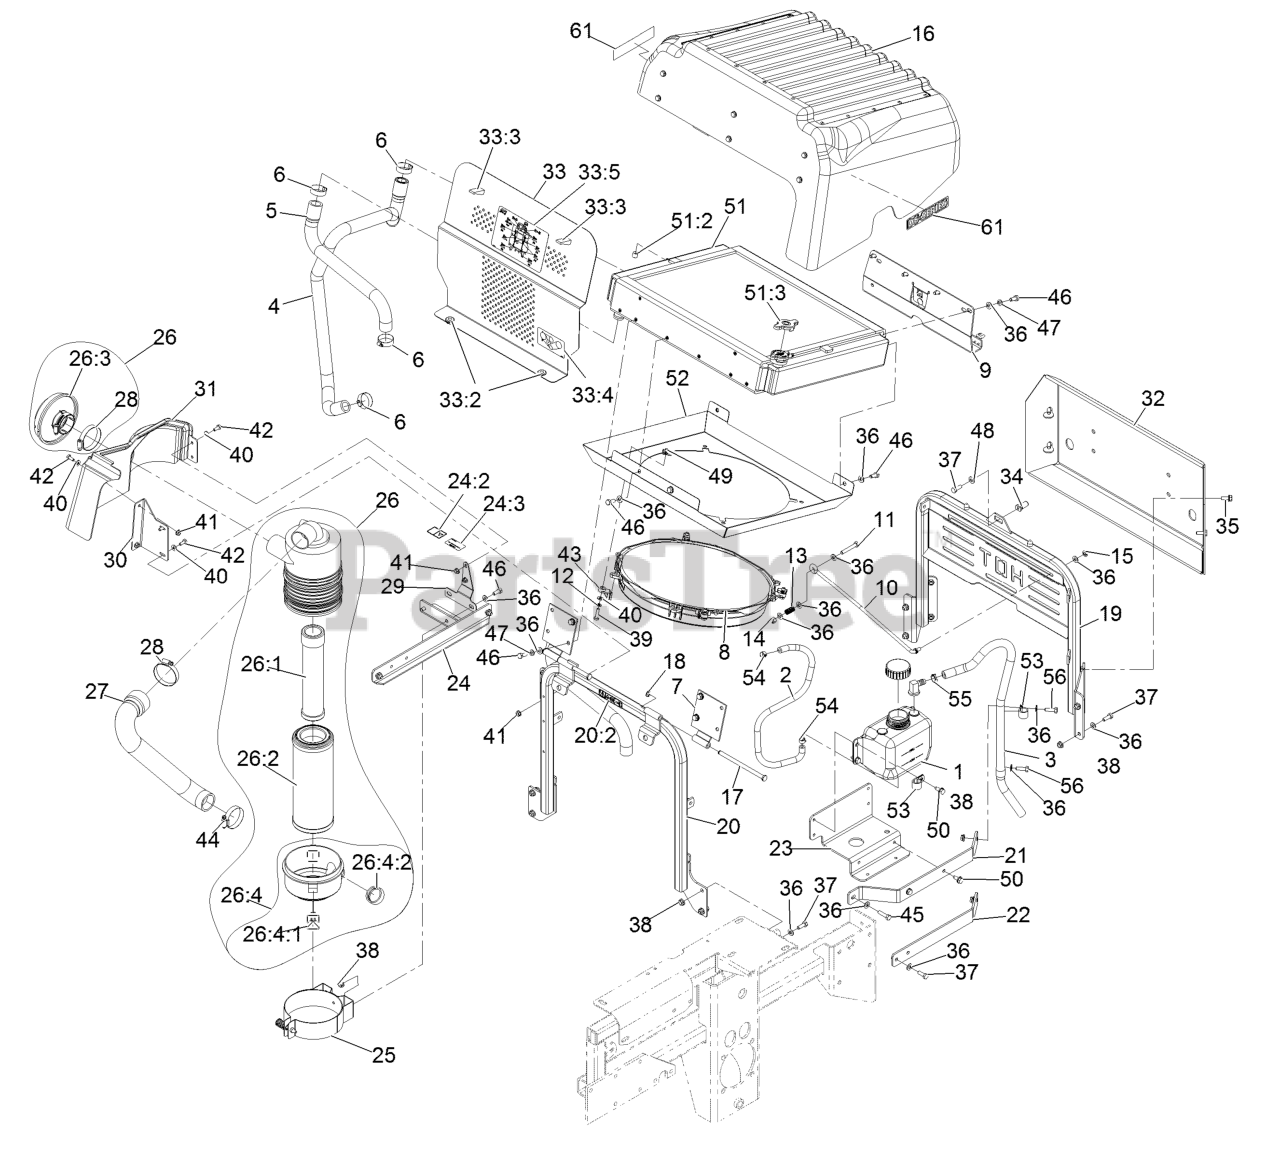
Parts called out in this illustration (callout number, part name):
1	TANK, OVERFLOW W/CAP
2	HOSE, .313 I.D.X 25.0 REI
3	HOSE, .500 I.D. X 30" EPD
4	HOSE,RADIATOR LOWER D902
5	HOSE,RADIATOR UPPER D902(
6	CLAMP-HOSE
7	WLD,HINGE PLATE
8	FAN- ELECTRIC
9	ASM-LATCH PLATE
10	ROD,PROP
11	SCREW-HH
12	SCREW-HH
13	SPRING,LOCK PIN
14	NUT-LOCK, NI
16	HOOD ASM, D902
19	WLD,REAR GUARD
20	ASM, RAD. MOUNT W/ DECALS
20:2	DECAL-DANGER
22	RIB, BOTTOM
23	BRACKET, BOTTLE-HYDRO TAN
24	Wld, Air Cleaner Mount
24	ASM,AIR CLNR BRKT W/DECAL
24:2	DECAL-WARNING
24:3	DECAL-CAUTION
25	BRACKET-FILTER, AIR
26	FILTER-AIR
26:1	FILTER-AIR, SAFETY
26:2	FILTER-AIR
26:3	HOOD-CLEANER, 2" AIR INTA
26:4	COVER-FILTER, AIR
26:4:1	CLIP-CLEANER, AIR
26:4:2	EJECTOR, NELSON AIR CLEAN
27	HOSE,AIR INTAKE D902(8015
28	CLAMP-HOSE
29	BRACKET,REAR COVER
30	BRACKET,FRONT COVER
31	PANEL, SIDE
32	WLD,REAR BUMPER
33	ASM,PANEL W/ DECALS LXS L
33:2	GROMMET
33:3	LATCH-SWELL
33:4	DECAL-BELT PUMP ROUTING
33:5	Decal-Service Aid
34	PIN,LATCH
35	SCREW-HHF
36	WASHER-PLAIN
37	SCREW-HH
39	SCREW-HH
40	WASHER-FLAT
42	SCREW-HH
43	MOUNT,FAN
44	CLAMP-HOSE
45	SCREW-HH
46	SCREW-HH
47	WASHER-LOCK
48	WASHER-SPRING
49	Nut-Retainer-Panel 1/4-20
50	Screw-HWH 5/16-18 X 3/4 Tf
51	RADIATOR ASM, AL D902
51:2	PLUG-PIPE
51:3	CAP-RADIATOR
52	FAN SHROUD,16
53	CLIP-LOOM
54	CLAMP-HOSE
55	CLAMP-HOSE
56	SCREW-HH
61	DECAL, DS SERIES
